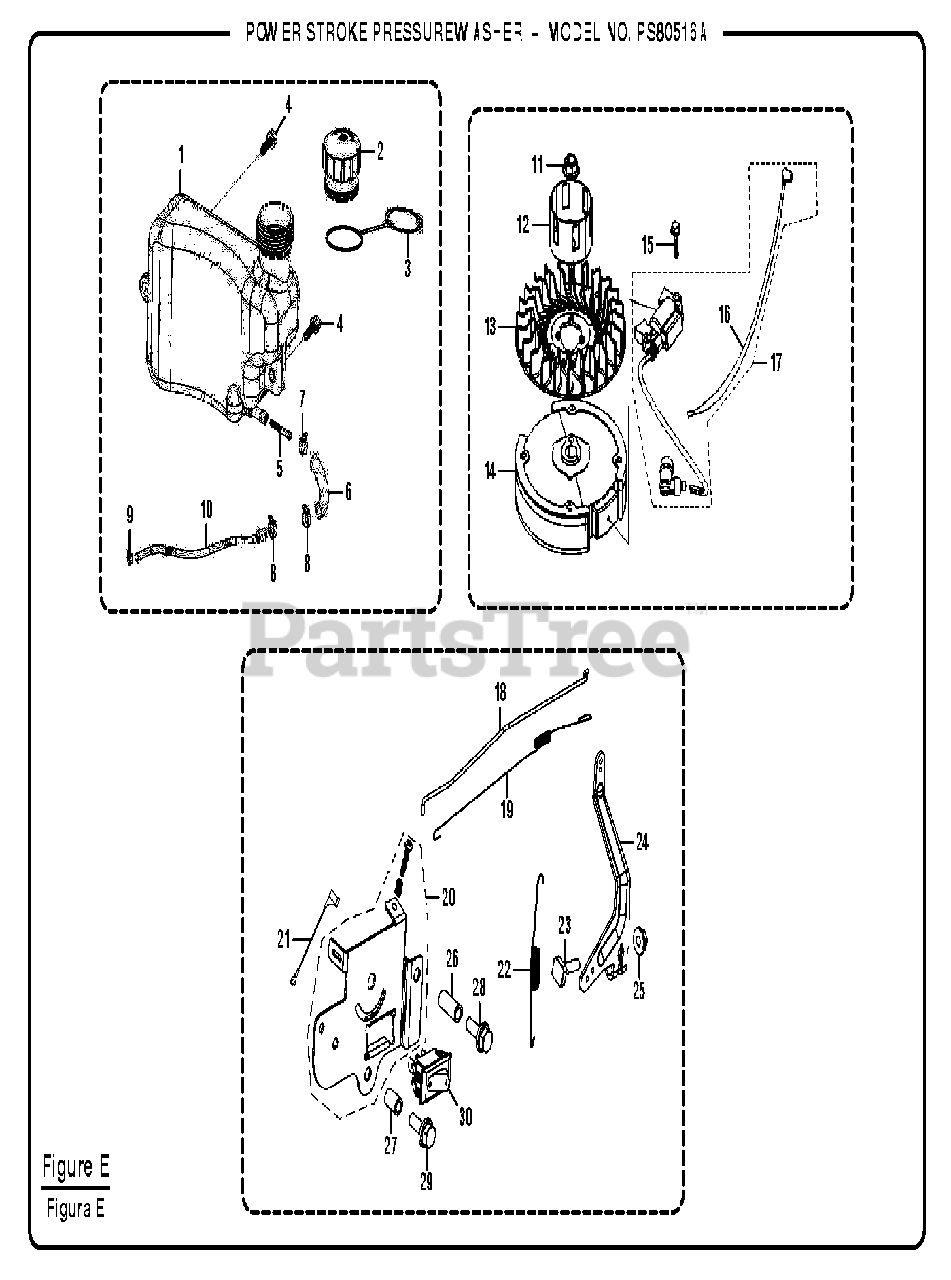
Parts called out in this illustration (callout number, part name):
1	Fuel Tank Assembly
14	Flywheel Assembly
16	Ignition Coil Stop Wire
19	Throttle Valve Returning Spring
20	Throttle Control Bottom Plate
21	Stop Engine Switch Ground Wire
22	Governor Spring
23	Governor Support Bolt
25	Governor Support Assembly
28	Hex Nut (M6)
29	Hex Nut (M6)
30	Engine Stop Switch
